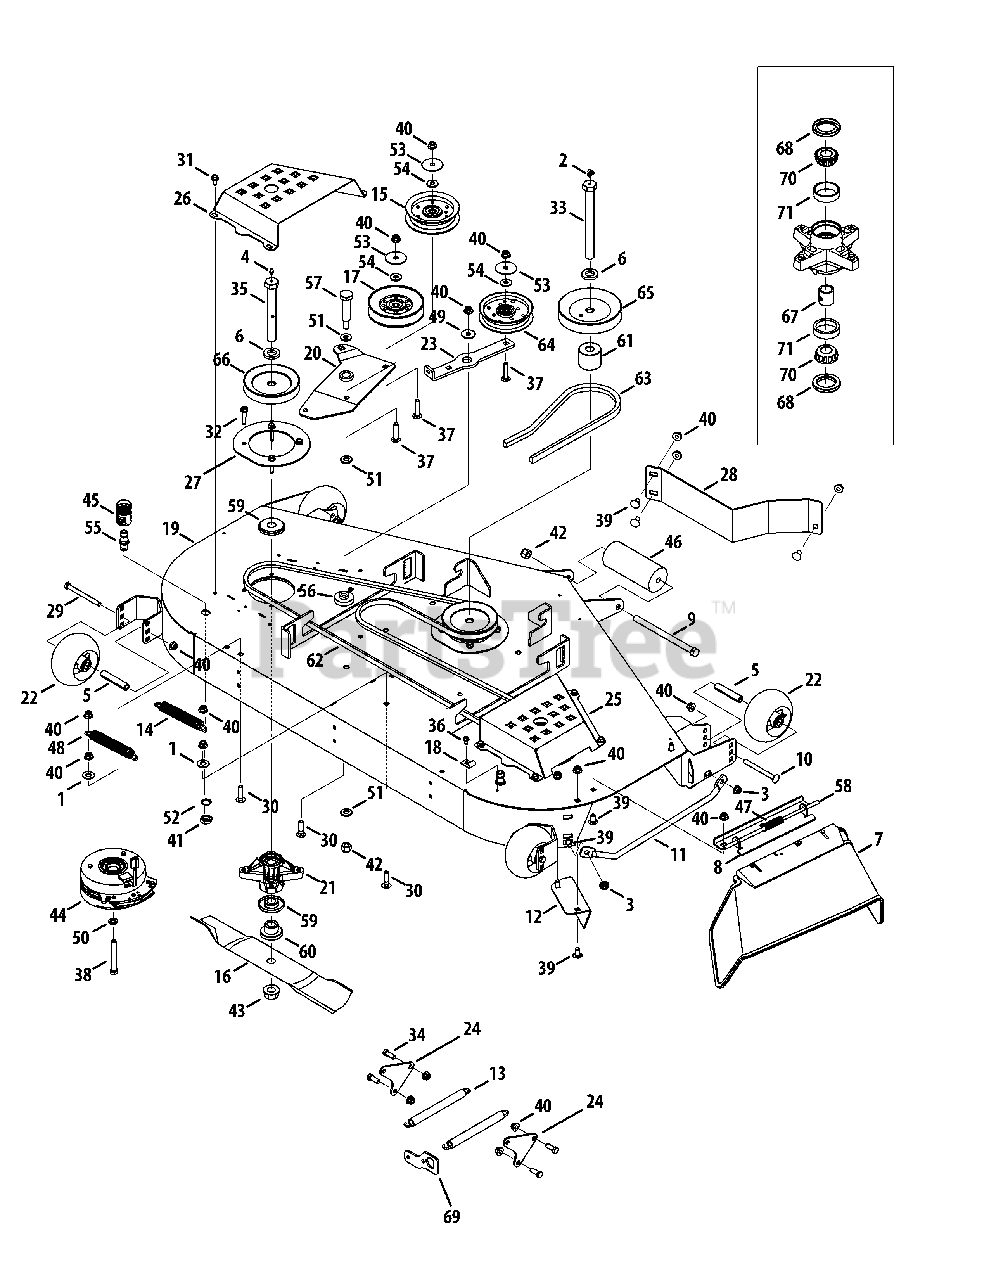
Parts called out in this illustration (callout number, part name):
1	Washer, .532 x 1.06 x .094
2	Grease Fitting, 1/4-28 x .788
3	Counterlock Flange Nut, 3/8-16
4	Straight Grease Fitting, 1/4-28
5	Spacer, .390 x .620 x 3.04
6	Spacer, .812 x 1.47 x .218
7	Fab Deck Deflector Chute
8	Deflector Chute Bracket
9	Hex Screw, 1/2-20 x 7.50
10	Carriage Bolt, 3/8-16 x 4.00
11	Fab Deck Chute Finger Guard
12	Deck Chute Baffle
13	Hook Ext. Spring, .75 x 7.89 x .14
14	Hook Ext. Spring, .94 x 7.57 x .14
15	Idler Pulley, 4.88
16	Hi-Lift Blade, 19.0
17	Idler Pulley, 5.06
18	Retainer Hook
19	54" Welded Deck
20	54" Idler Assembly
21	Deck Spindle Assembly
22	Deck Wheel
23	Deck Idler Arm
24	Spring Mount Plate
25	54" RH Belt Cover
26	54" LH Belt Cover
27	Spindle Reinforcement Plate
28	Standard Baffle
29	Hex Screw, 3/8-16 x 4.00
30	Carriage Bolt, 3/8-16 x 1.50
31	Hex Washer Screw, 5/16-18 x .750
32	Flange Hex TT Screw, 5/16-18 x 1.50
33	Hex Screw, 3/4-16 x 8.0
34	Hex Screw, 3/8-16 x 1.00
35	Hex Screw, 3/4-16 x 6.0
36	Hex Washer TT Screw, 1/4-20 x .500
37	Carriage Bolt, 3/8-18 x 1.75
38	Hex Screw, 7/16-20 x 3.50
39	Carriage Bolt, 3/8-16 x .75
40	Flange Lock Nut, 3/8-16
41	Hex Nut, M16-1.5
42	Nut, Hexlk, 1/2-20, Gr2, Nylon
43	Flange Lock Nut, 3/4-16
44	Electric PTO Clutch
45	Water Nozzle Adapter
46	Front Roller
47	Torsion Spring
48	Extension Spring, .91 x 7.33
49	Washer, .411 x 1.25 x 1.00
50	Lock Washer, 7/16
51	Flat Washer, .390 x 1.500 x .134
52	Lock Washer, 17 x 23.8 x 1.95
53	Flat Washer, .406 x 1.92 x .060
54	Washer, .406 x 1.00 x .105
55	Water Deck Nozzle
56	Shoulder Spacer, .854 x .280
57	Shoulder Bolt, 3/8-16 x .74 x 2.47
58	Chute Deflector Rod
59	Deck Spindle Spacer
60	Spindle Spacer, .76 x 2.0 x 1.1
61	Spacer, .760 x 2.00 x 1.69
62	V-Belt
64	Idler Pulley, 4.25
65	V-Type Pulley
66	V-Type Pulley
67	Bearing Spacer
69	Spring Mount Bracket
70	Cone Bearing, .750"
71	Bearing Cup, .750"
